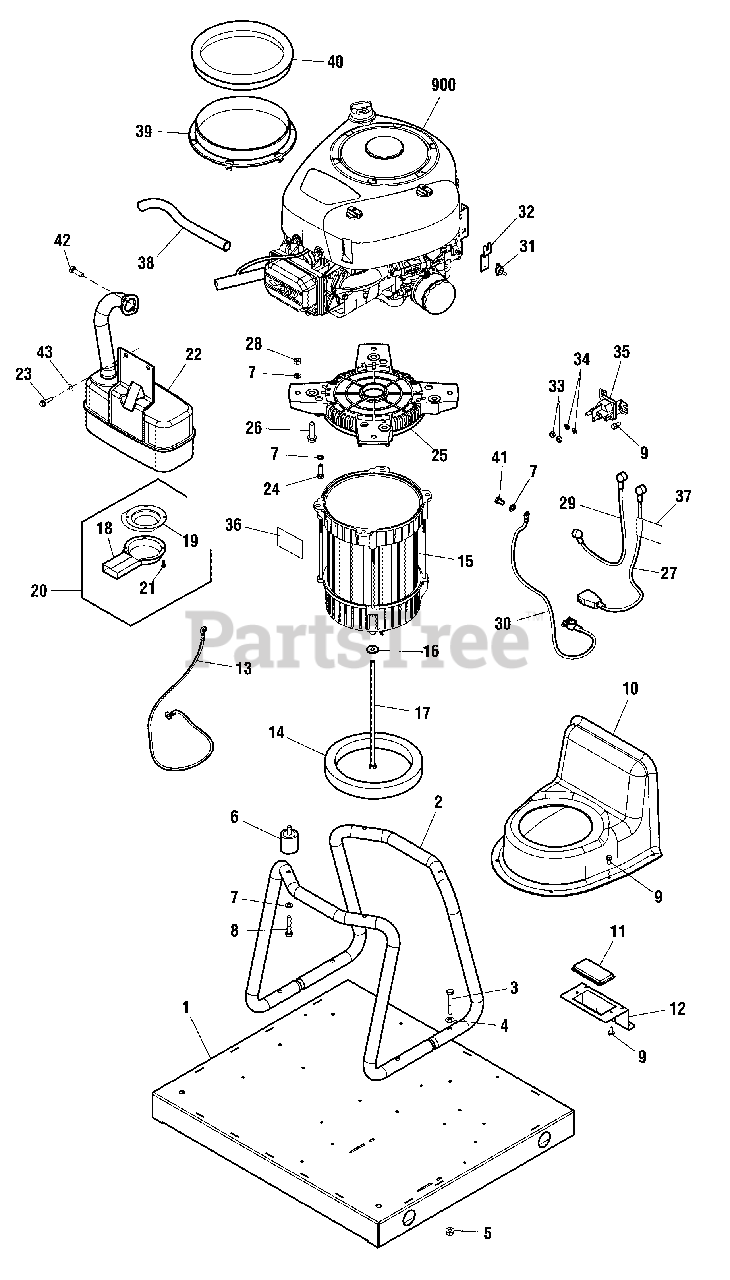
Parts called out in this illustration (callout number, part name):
3	* CAPSCREW-HEX HEAD 5/16-18 x 2
4	* WASHER-FLAT M8 (or 5/16)
5	* NUT-FLANGE 5/16-18
6	MOUNT-VIBRATION
7	* WASHER-LOCK M8 (or 5/16)
8	* CAPSCREW-HEX HEAD M8-1.25 x 35
9	BOLT
11	REGULATOR-VOLTAGE
15	ALTERNATOR
19	ARRESTOR-SPARK
20	KIT-DEFLECTOR MUFFLER
24	* CAPSCREW-HEX HEAD 5/16-18 x 1
26	SCREW
27	WIRE
28	* NUT, HEX M8-1.25
32	PLATE-TEMP SWITCH
33	* NUT-1/4-20
34	* WASHER-LOCK M6 (or 1/4)
35	SOLENOID-STARTER
36	DECAL SHEET-WARNINGS
37	DECAL SHEET-WARNINGS
39	COLLAR-AIR INLET
43	* WASHER, Flat, M6 (or 1/4)
900	** ENGINE
